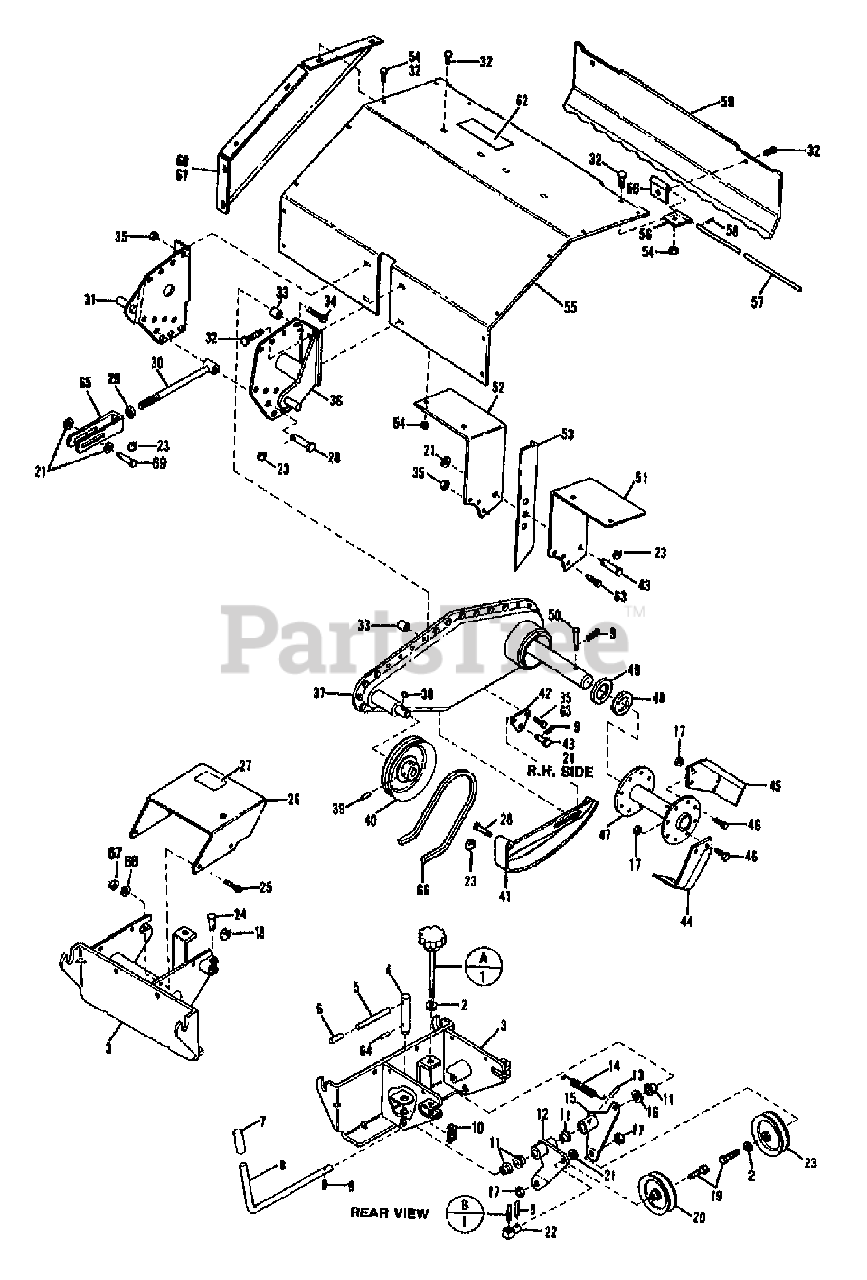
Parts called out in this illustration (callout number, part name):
1	ASSM-KNOB ADJ
2	WASHER-FLAT 3/8 SAE
4	PIN-HITCH
5	PIN-ROLL .312X4.00 ZP
6	GRIP-HANDLE
7	GRIP-HANDLE
8	SHAFT-IDLER
9	PIN-COTTER .120X1.00 ZP
10	SPRING-COMPRESSION
11	BEARING-FLANGE
12	ASSM-IDLER ARM
13	PIN-ROLL .188X1.0
15	ASSM-IDLER ARM
16	WASHER-1.305X.649X.098 ZP
17	NUT-LOCK 3/8-16
18	RING-CIRCLE COTTER
19	SCR-HH 3/8-16X1.75 G5 ZP
20	PULLEY-IDLER ZP
21	WASHER-1.06X.531X.1 ZP
22	BLOCK-PIVOT
23	PULLEY-IDLER
24	PIN-CLEVIS .5X1.437 ZP
25	SCR-HH 1/4-20X.75 G5 ZP
26	COVER-BELT W/DECAL
27	DECAL-OPEI CAUTION
28	PIN-CLEVIS .5X2.5 ZP
29	NUT-HEX/JAM 5/8-18 ZP
31	PLATE-MOUNTING CHAIN CASE
32	SCR-CARR 5/16-18X.75
33	SPACER-.384X.268X.788 ZP
34	SCR HH 1/4-20X2.5 G5 ZP
35	NUT-HT LK 1/4-20
36	PLATE-CHAIN CASE LH
37	ORDER PIECE PARTS
38	KEY-WOODRUFF .188X.75
39	SCR-SET HXSKT 5/16-18X.38
40	SHEAVE-DRIVE
41	ASSM-DEPTH SHOE
43	PIN-CLEVIS .5X1.06 ZP
44	TINE
46	SCR-HH 3/8-16X1.0 G5 ZP
47	ASSM-TINE HOLDER
48	SEAL-DUST (OUTER)
49	SEAL-DUST 2.31 DIA
50	PIN-CLEVIS .437X2.06 ZP
51	SUPT-HOOD LH
52	SUPT-HOOD RH
54	NUT-HFLK 5/16-18 ZP
58	PIN-COTTER .09X.75 ZP
59	BOARD-LEVELING
62	DECAL-LOGO
63	SCR-HH 1/4-20X1.0
64	PIN-ROLL .125X1.25
65	ASSM-CLEVIS
67	NUT-HEX 1/4-20 ZP
68	WASHER-LK .25 ZP
69	PIN-CLEVIS .5X1.75 ZP
